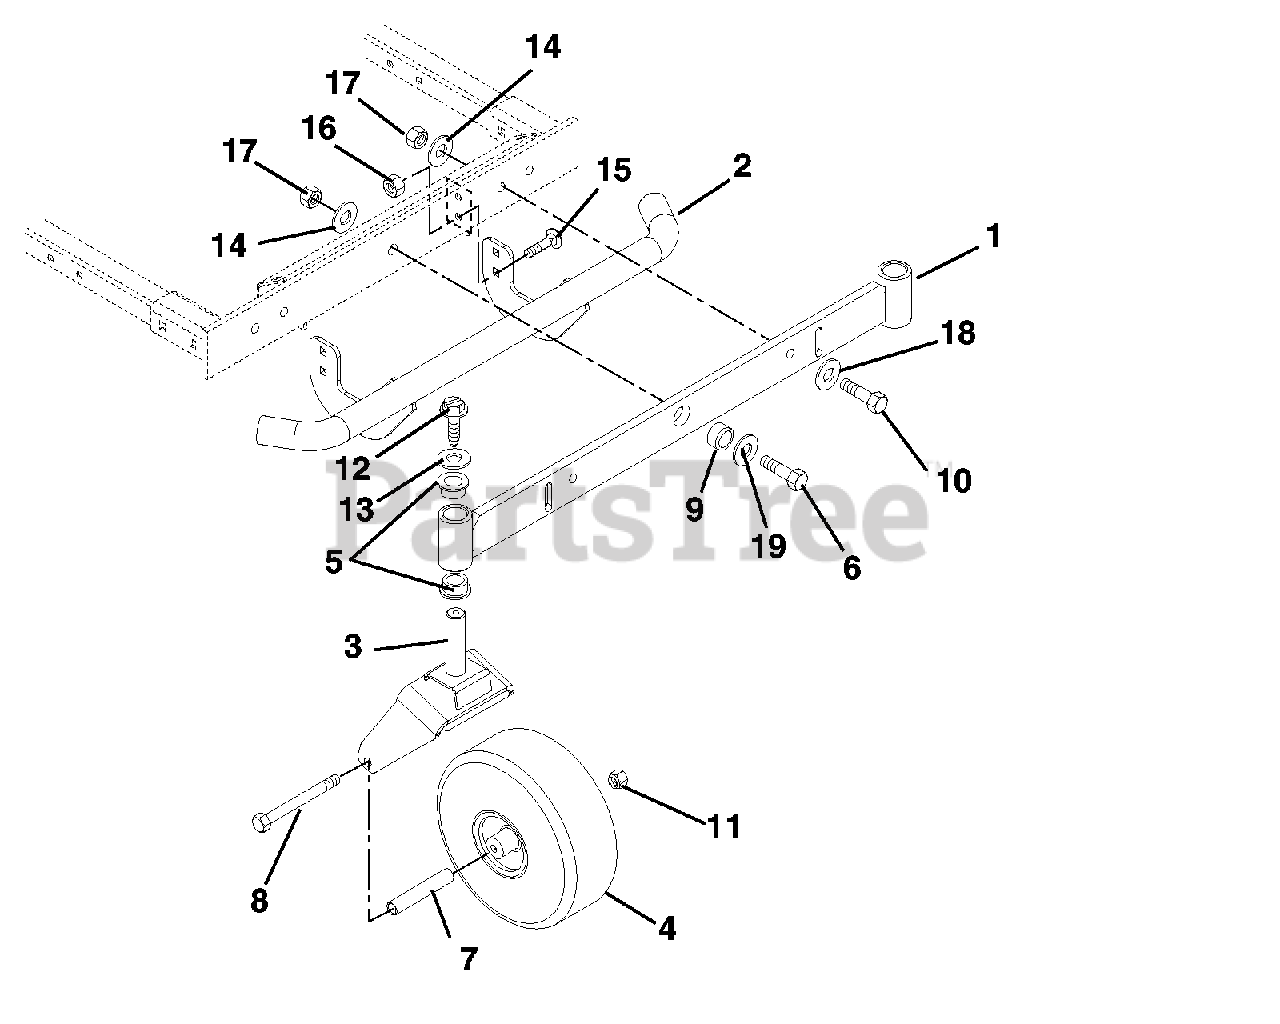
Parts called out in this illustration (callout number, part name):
1	WMT, FRONT AXLE
2	BUMPER-ZOOM
3	FORK - CASTER
4	ASSY-TIRE 4 X 11 - 4 PLY
5	BSHG-FLG 1.00X1.25X1.50X1.50EP
6	BLT-HEX .62-11X2.50 GR5 BKZC
7	BUSH.,CASTER FORK
8	@BLT-HEX .50-13X6.50 GR5 YWZC
9	BUSHING, AXLE PIVOT
10	BLT-SHLDR .75 .625-11X2.12SHCS
11	@NUT-LK-TOP-FLG .50-13 YWZC
12	SCR-TAP .38-16X1.25 HWH TR BZC
13	WSHR-FL-STL .38X1.50X.12 BKZC
14	WSHR-FLT .640X1.75X.250 YWZC
15	BLT-RDHDSQNK .38-16X1.00 G5BZ
16	NUT-LK-TOP-FLG .38-16 BLKZC
17	@NUT-LK-NYL .625-11 YWZC
18	@WSHR-FL-STL.812X1.50X.135YWZC
19	@WSHR-FL-STL.688X1.75X.134 YWZ
